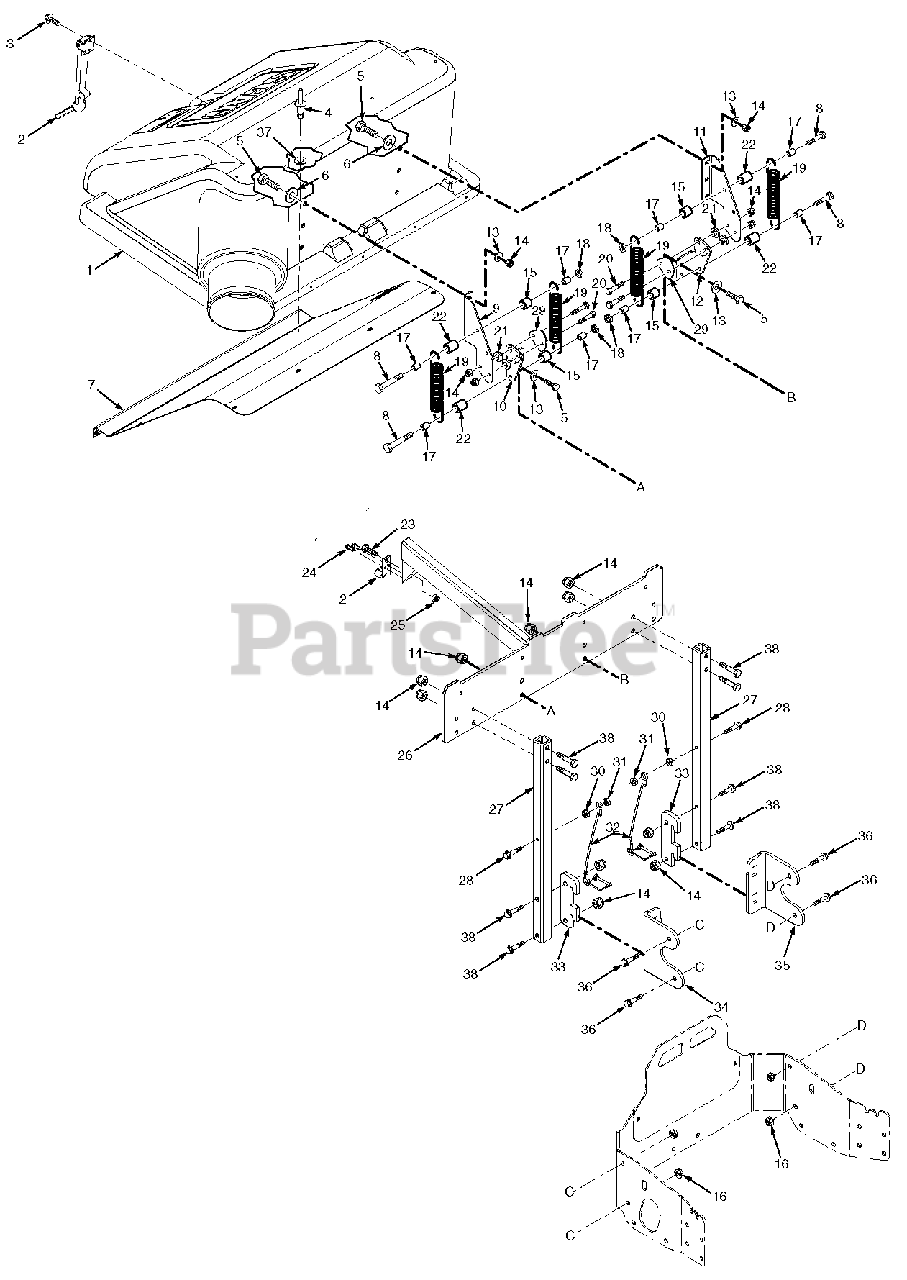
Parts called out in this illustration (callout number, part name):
1	Hood Assembly
2	Latch
3	Screw, #10-32 x 3/4"
3	Flatwasher, 3/8-.193 x .496 x .048
3	Nut, Elastic Stop #10-32
4	Pop Rivet, 3/16 x .652
5	Bolt, Hex Head 3/8-16 x 1-1/4"
6	Flatwasher, 3/8-.406 x 1.5 x 7 Ga.
7	Screen, GC Hood
8	Bolt, Hex Head 3/8-16 x 3-3/4"
9	Hinge, Upper RH
10	Hinge, Lower RH
11	Hinge, Upper LH
12	Hinge, Lower LH
13	Flatwasher, 3/8-391 x .938 x .105
14	Nut, Elastic Stop 3/8-16
15	Spacer
16	Nut, Serrated Flange 3/8-16
17	Sleeve
18	Nut, Center Lock 3/8-16
19	Spring
20	Bolt, Hex Head 3/8-16 x 1-1/2"
21	Bushing, Hopper Pivot
22	Spacer
23	Bolt, Hex Head 5/16-18 x 3/4"
24	Pop Rivet, 3/16 x .402
25	Nut, Elastic Stop 5/16-18
26	Frame Weldment, Bag Support
27	Tube, Grass Catcher Mount
28	Bolt, Hex Head 1/4-20 x 2"
29	Guard, Hinge
30	Nut, Serrated Flange 1/4-20
31	Nut, Center Lock 1/4-20
32	Snap Pin Assembly
33	Latch, GC
34	Bracket, GC Mount RH
35	Bracket, GC Mount LH
36	Bolt, Hex Head 3/8-16 x 1"
37	Flatwasher, 3/16-.196 x .469 x .048
38	Bolt, Hex Head 3/8-16 x 2-1/4"
